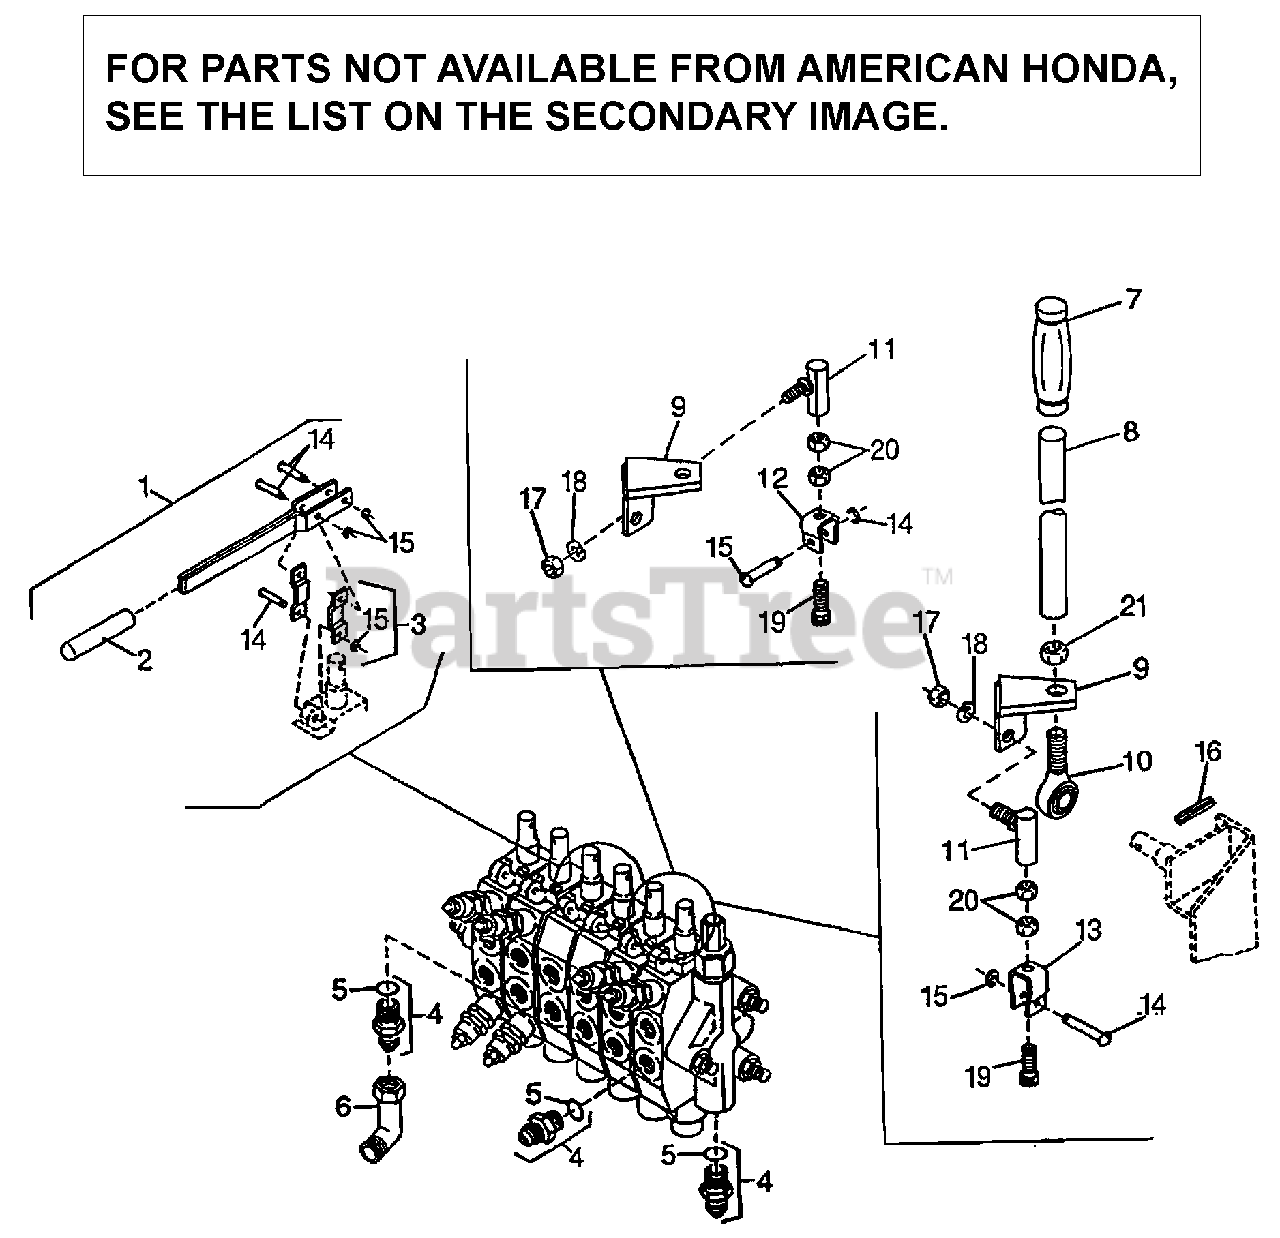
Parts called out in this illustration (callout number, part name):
2	HANDLE, RUBBER
7	GRIP (.63X1.06X5.0)
8	HANDLE, CONTROL
9	WELDMENT ASSY., HANDLE ARM
10	ROD END, MALE (7/16) (NF)
11	JOINT, BALL (5/16") (NF)
12	SPOOL, CLEVIS VALVE (.69")
13	SPOOL, CLEVIS VALVE (1.0")
15	O-RING (OUTER) (.025X.156")
